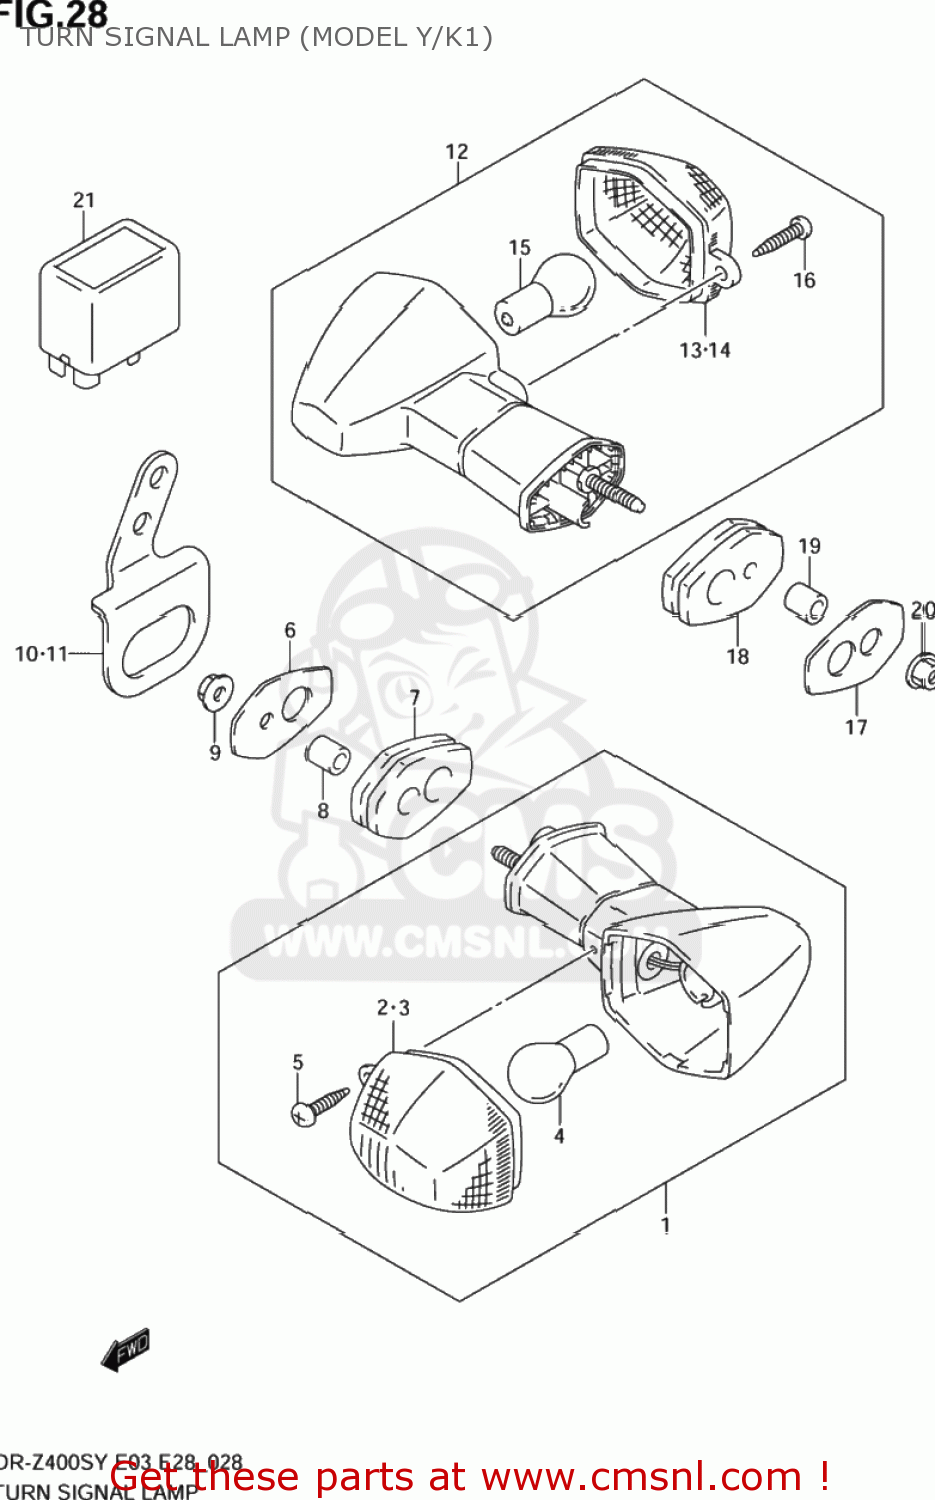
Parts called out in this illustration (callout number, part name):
1	LAMP ASSY,FR TURN SIGNAL,R
2	LENS
3	LENS
4	BULB(12V21W)
5	SCREW
6	PLATE,FR TURNSIGNAL
7	CUSHION,FR TURNSIGNAL
8	SPACER(5.5X9.5X10)
9	NUT
10	BRACKET,FR TURNSIGNAL,R
11	BRACKET,FR TURNSIGNAL,L
12	LAMP ASSY,RR TURNSIGNAL,R
13	LENS
14	LENS
15	BULB(12V21W)
16	SCREW
17	PLATE,FR TURNSIGNAL
18	CUSHION,FR TURNSIGNAL
19	SPACER(5.5X9.5X10)
20	NUT
21	RELAY ASSY,TURNSIGNAL LAMP
